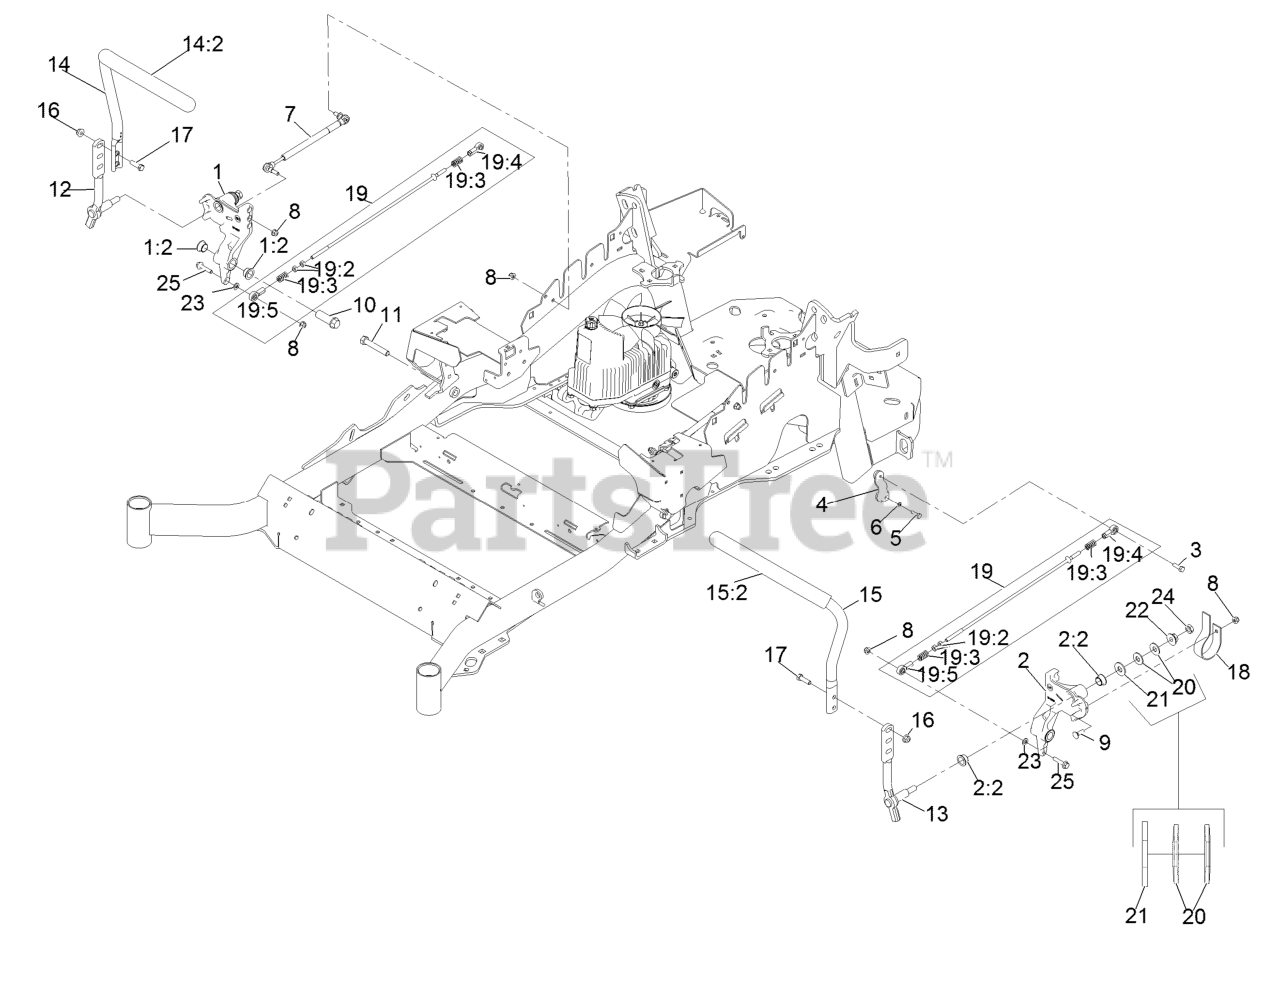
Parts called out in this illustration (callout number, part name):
1	RH Motion Control And Bushing ASM
1:2	Bushing-Flanged
2	LH Motion Control And Bushing ASM
2:2	Bushing-Flanged
3	Screw-HH 5/16-18 X 1 W/Patch
4	Arm-Control, Pump
5	Screw-HH 1/4-20 X 7/8
6	Washer-Spring Disc 1/4
7	Damper-Control, Motion
8	Nut-Nyloc 5/16-18 Flg
9	Bolt-Carriage 5/16-18 X 1
10	Hub-Threaded
11	Screw-HH 1/2-13 X 3
12	Lever-Control Motion, RH
13	Lever-Control Motion, LH
14	RH Steering Handle ASM
14:2	Grip-Control, Lever
15	LH Steering Handle ASM
15:2	Grip-Control, Lever
16	Nut-Nyloc 3/8-16 Flg
17	Screw-HH 3/8-16 X 1 1/4
18	Spring-Leaf
19	Front Pump Linkage ASM
19:2	Nut-Hex 5/16-24
19:3	Spring-Compression
19:4	Balljoint
19:5	Balljoint
20	Washer, Spring Disc 1/2
21	Washer
22	Nut-Hex 1/2-13 Flange
23	Washer-5/16 SAE
24	Nut-Jam 1/2-13
25	Screw-Hex Flange 5/16-18 X 1 1/2
